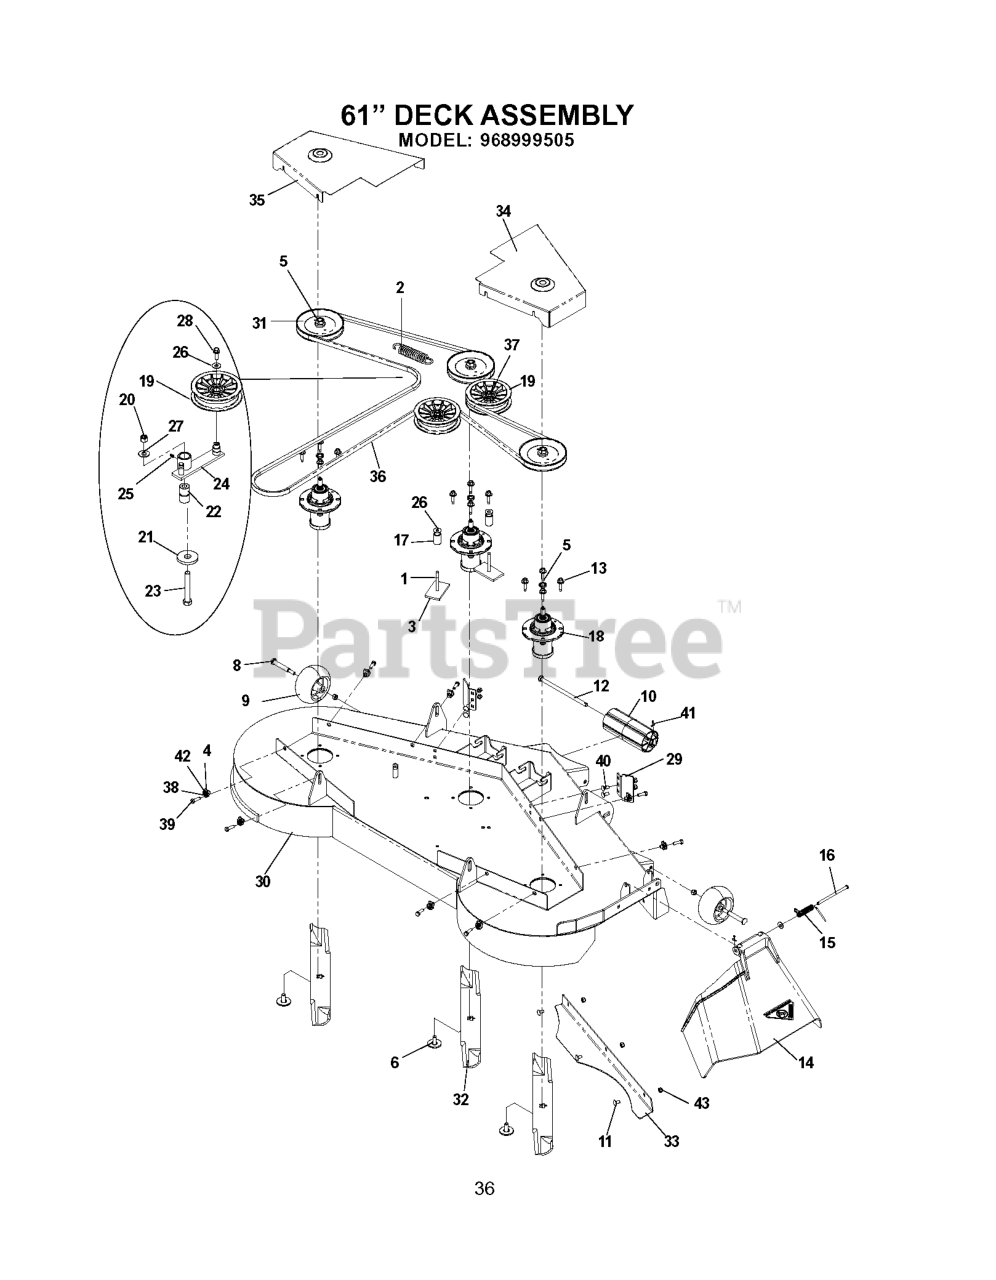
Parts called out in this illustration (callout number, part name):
1	HCS 3/8C X 3
3	SUPPORT PLATE
4	U-CLIP 5/16-18 NUT RETAINER
5	WASHER-SPACER
6	BOLT 7/16 ASM BLADE
7	LOCKNUT - 9/16
8	BOLT, SHOULDER
9	WHEEL GAGE DONUT
10	NOSE ROLLER 48"
11	CARRIAGE BOLT 5/16C X 5/8"
12	NOSE ROLLER ROD
13	WASHER HEAD SCREW
14	DISCHARGE CHUTE 61"
15	SPRING - TORSION
16	PIN-CLEVIS 5/16 DIA X 5.19 ZD
17	IDLER BUSHING
18	MANDREL.DECK.ASSEMBLY
19	IDLER
20	NUT 1/2-13 HEX NYLOC ZD
21	WASHER, SUPPORT
22	PIVOT BUSHING
23	HCS 1/2C X 3 1/4
25	ZERK
26	WASHER 3/8 FLAT
27	WASHER 1/2 FLAT
28	4CS 3/8C X 1 SERRATED HEAD
30	DECK W/DECALS 61" HUS
32	BLADE, 21"
33	CONFINEMENT PLATE 61
34	BELT SHIELD W/DECALS, 61" RT
35	BELT SHIELD W/DECALS,61" LT
36	BELT, DECK - ESTATE
37	NUT 3/8-16 NYLOC
38	WASHER.LOCK.HVY.HLCL.SPR.5/16
39	HCS 5/16C X 1
40	BOLT 5/16C X 3/4" CARRIAGE
41	RP_COTTER PIN 1/8 X 3/4
42	WASHER 5/16 FLAT
43	NUT 5/16 NYLOC
